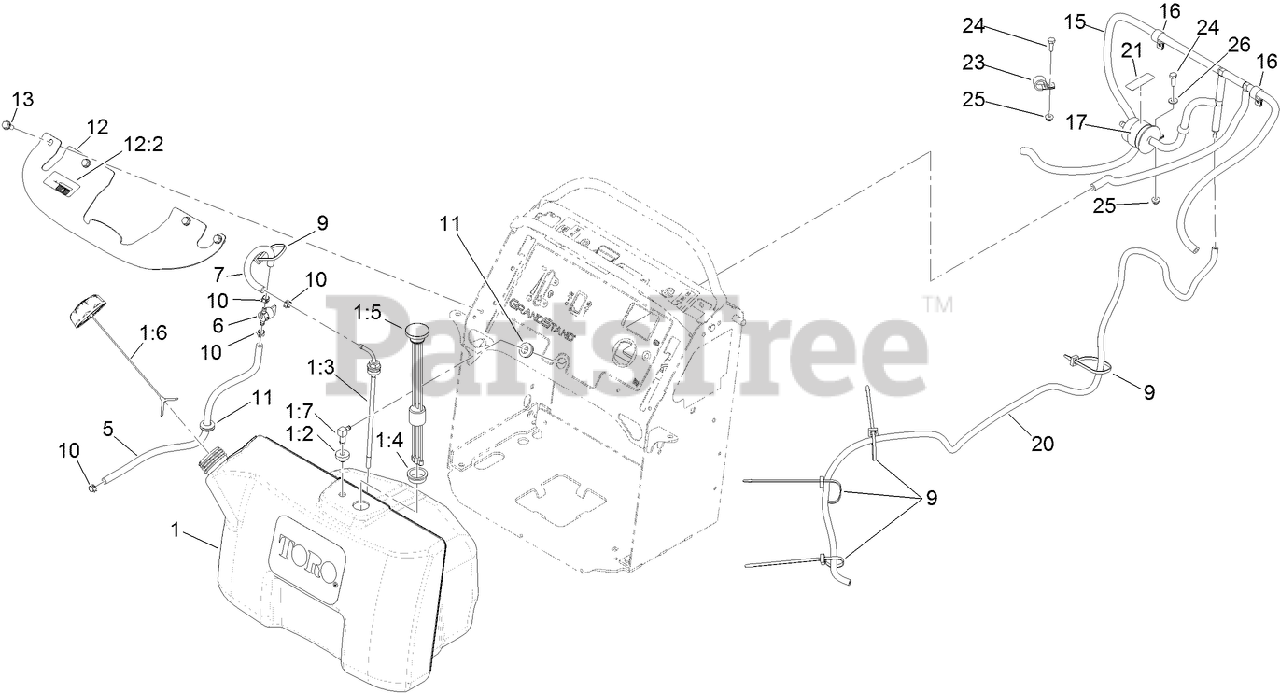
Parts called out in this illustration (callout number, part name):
1	TANK ASM
1:2	BUSHING
1:3	ELBOW-90 DEG
1:4	GROMMET
1:5	GUAGE-FUEL
1:6	CAP-FUEL, RATCHETING
1:7	FITTING-FUEL, BULKHEAD
5	HOSE-FUEL
6	VALVE-FUEL
7	HOSE-FUEL
9	TIE-CABLE
10	CLAMP-HOSE
11	GROMMET
12	BRACKET-TANK
12:2	DECAL-FILL, FUEL
13	SCREW-HWHTF
15	VENT HOSE ASM
16	CLAMP-CABLE
17	CLAMP-R
20	HOSE-FUEL
21	DECAL-FILTER, EMISSIONS
23	CLAMP-CABLE
24	SCREW-HH
25	NUT-HF
26	WASHER-FLAT
